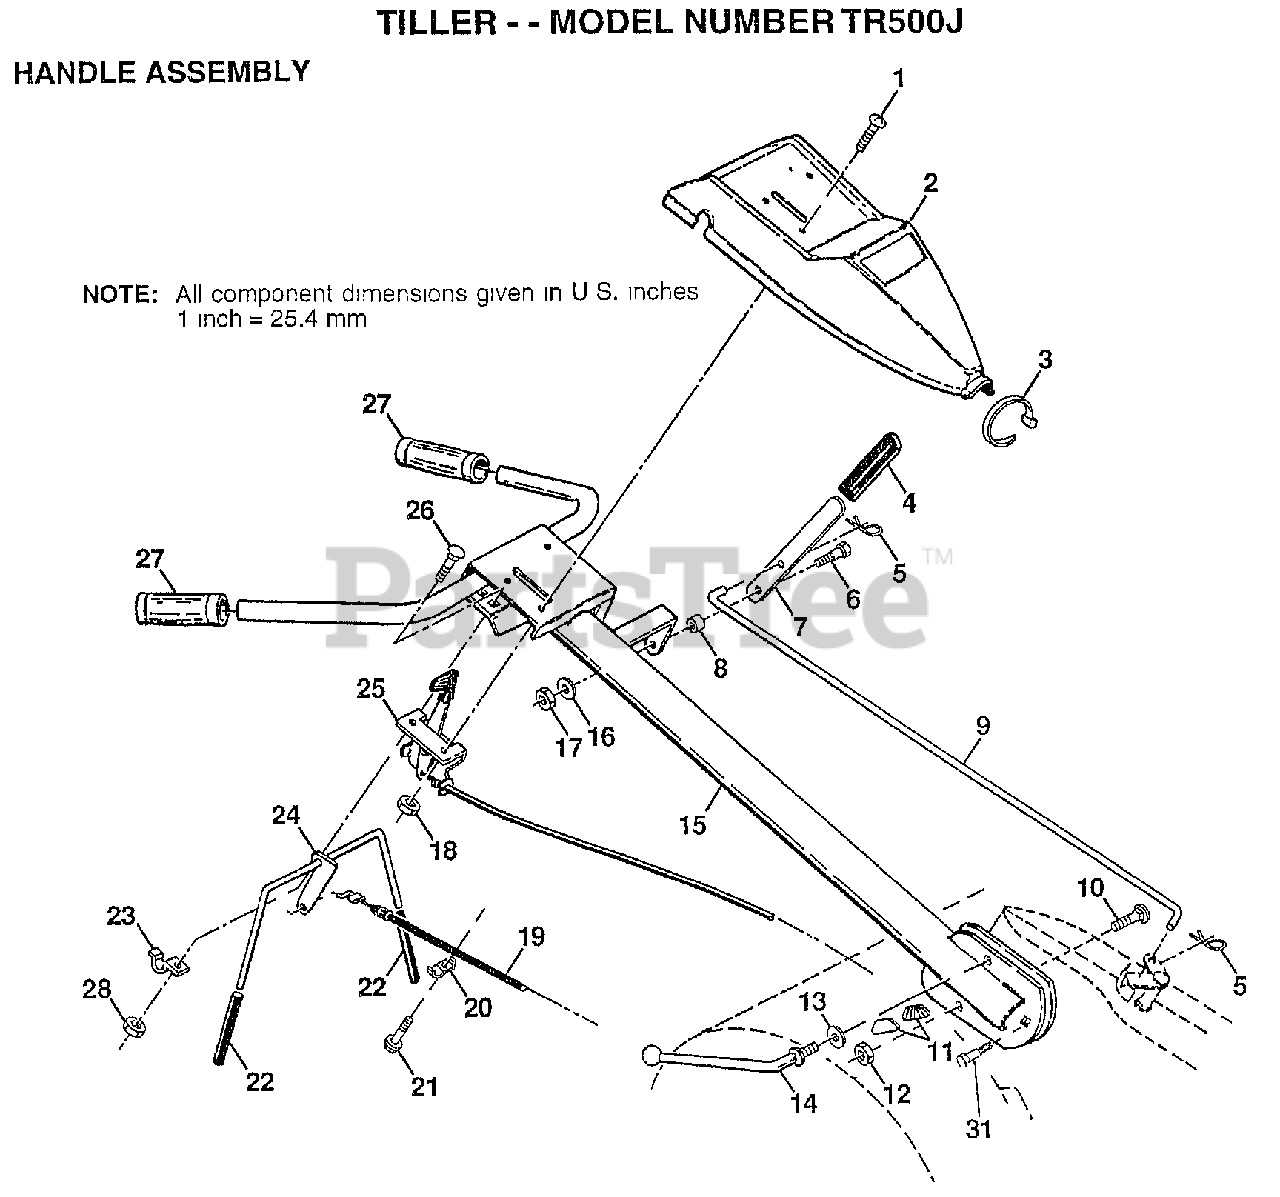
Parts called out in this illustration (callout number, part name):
1	SCREW.PNHD.10-24
2	"PANEL,CONT TI"
3	TIE CABLE CRT
4	GRIP T
5	RETAINER M
6	SHOULDER BOLT ST
7	SHIFT HANDLE CRT
8	GROMMET CRT
9	SHIFT ROD CRT
10	BOLT D
11	LOCK CRT
12	LOCKNUT
13	WASHER CRT
14	LEVER LOCK CRT
16	LOCKWASHER
19	CABLE.CLUTCH.48.Z
20	CONDIUT CLIP T
22	GRIP BAR CRT
24	"ASSY CONTROL, BAR"
25	"CONT,THROTTLE"
26	BOLT
27	GRIP NUB SNGL HDL
28	NUT
31	BOLT PIVOT
